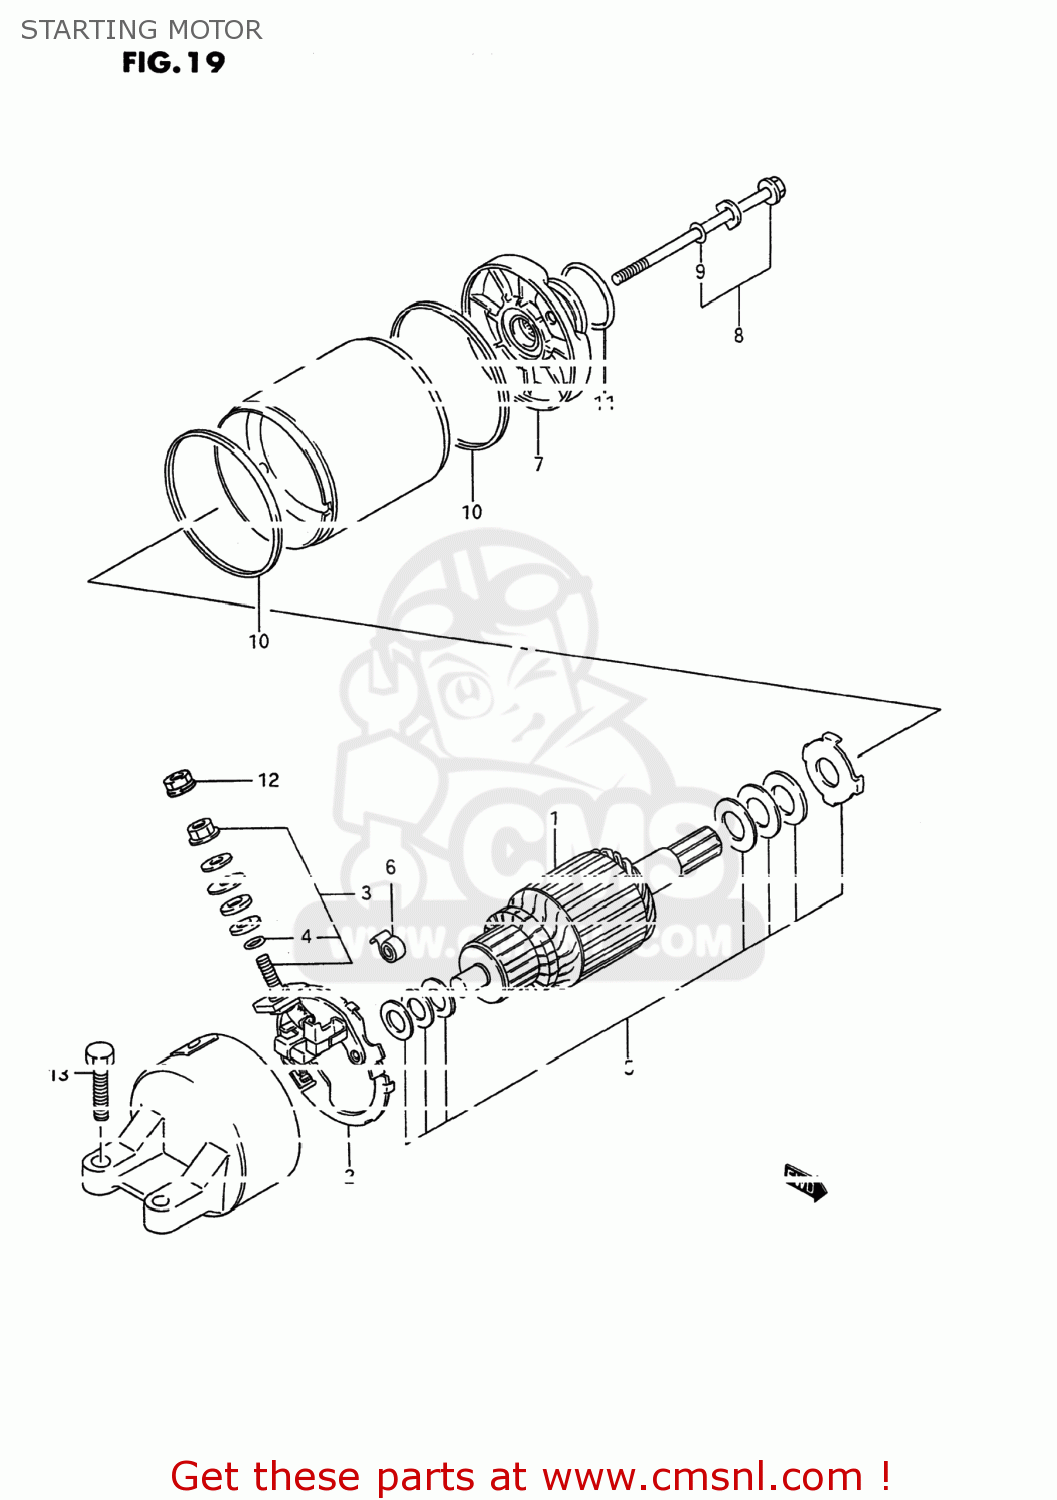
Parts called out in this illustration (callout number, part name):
1	ARMATURE
2	HOLDER SET,BRUSH
3	TERMINAL SET,BRUSH,PLUS
4	O RING
5	SHIM SET,STARTING MOTOR
6	SPRING,BRUSH
7	BRACKET ASSY,FR
8	BOLT SET,STARTING MOTOR
9	O RING
10	O RING
11	O RING(D:3,ID:24.5)
12	NUT
13	SCREW (6X25)
